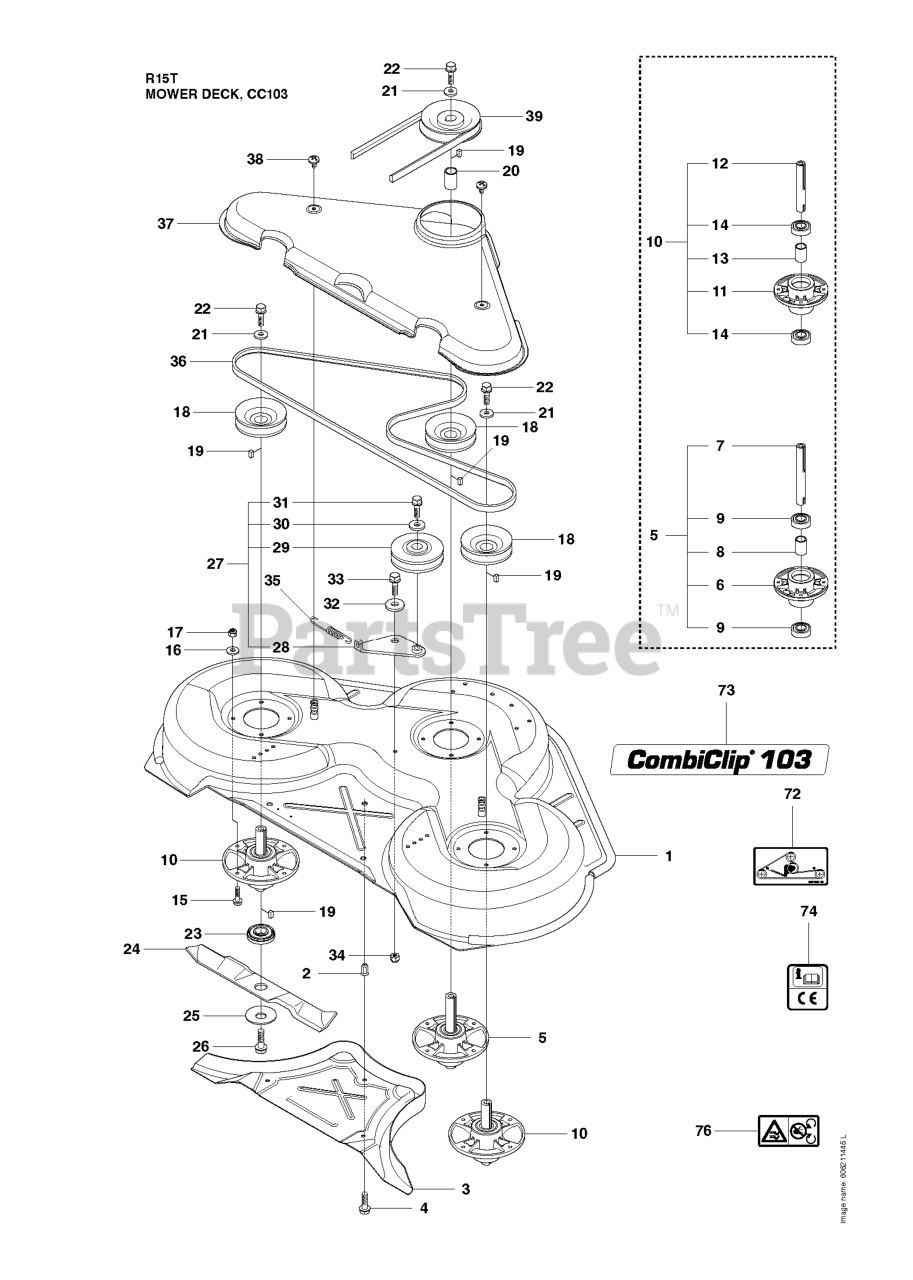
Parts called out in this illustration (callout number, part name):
1	CUTTING DECK RIDER
5	SPINDLE ASSY
6	BEARING HOUSING
10	RP SPINDLE ASSY
11	BEARING HOUSING
16	WASHER BRB 8.4X17
17	LOCKNUT M8
25	WASHER
27	BELT TENSIONER ASSY
28	BELT TENSIONING ARM
32	WASHER
34	LOCKNUT M8
